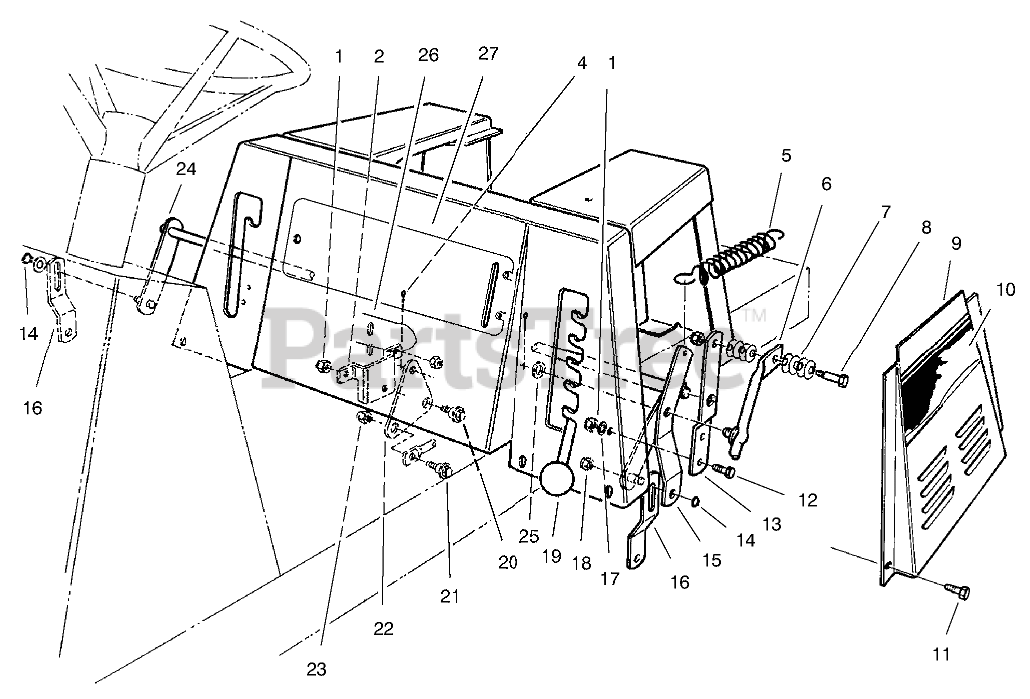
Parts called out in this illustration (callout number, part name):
1	NUT-LOCK, NI
2	BRKT-B.CRANK MTG
4	PIN-COTTER
5	SPRING-EXTENSION
6	HOC LEVER WA (BLACK)
7	WASHER-BELLEVILLE
8	BOLT-SHOULDER
9	PANEL-LH SEAT BASE
10	DECAL - SIDE
11	SCREW-HH
12	SCREW-HH
13	BRKT-HOC SUPT
14	RING-RETAINING
15	BRKT-HOC ENGAGE
16	LINK-SUSP
17	WASHER-PLAIN
18	NUT-LOCK, NI
20	SCREW-SHOULDER
21	SCREW-SHOULDER
22	BELLCRANK
23	NUT-HEX
24	HOC LEVER WA (BLACK)
25	WASHER-FLAT
26	DECAL - USA
27	DECAL-CONTROL PANEL
